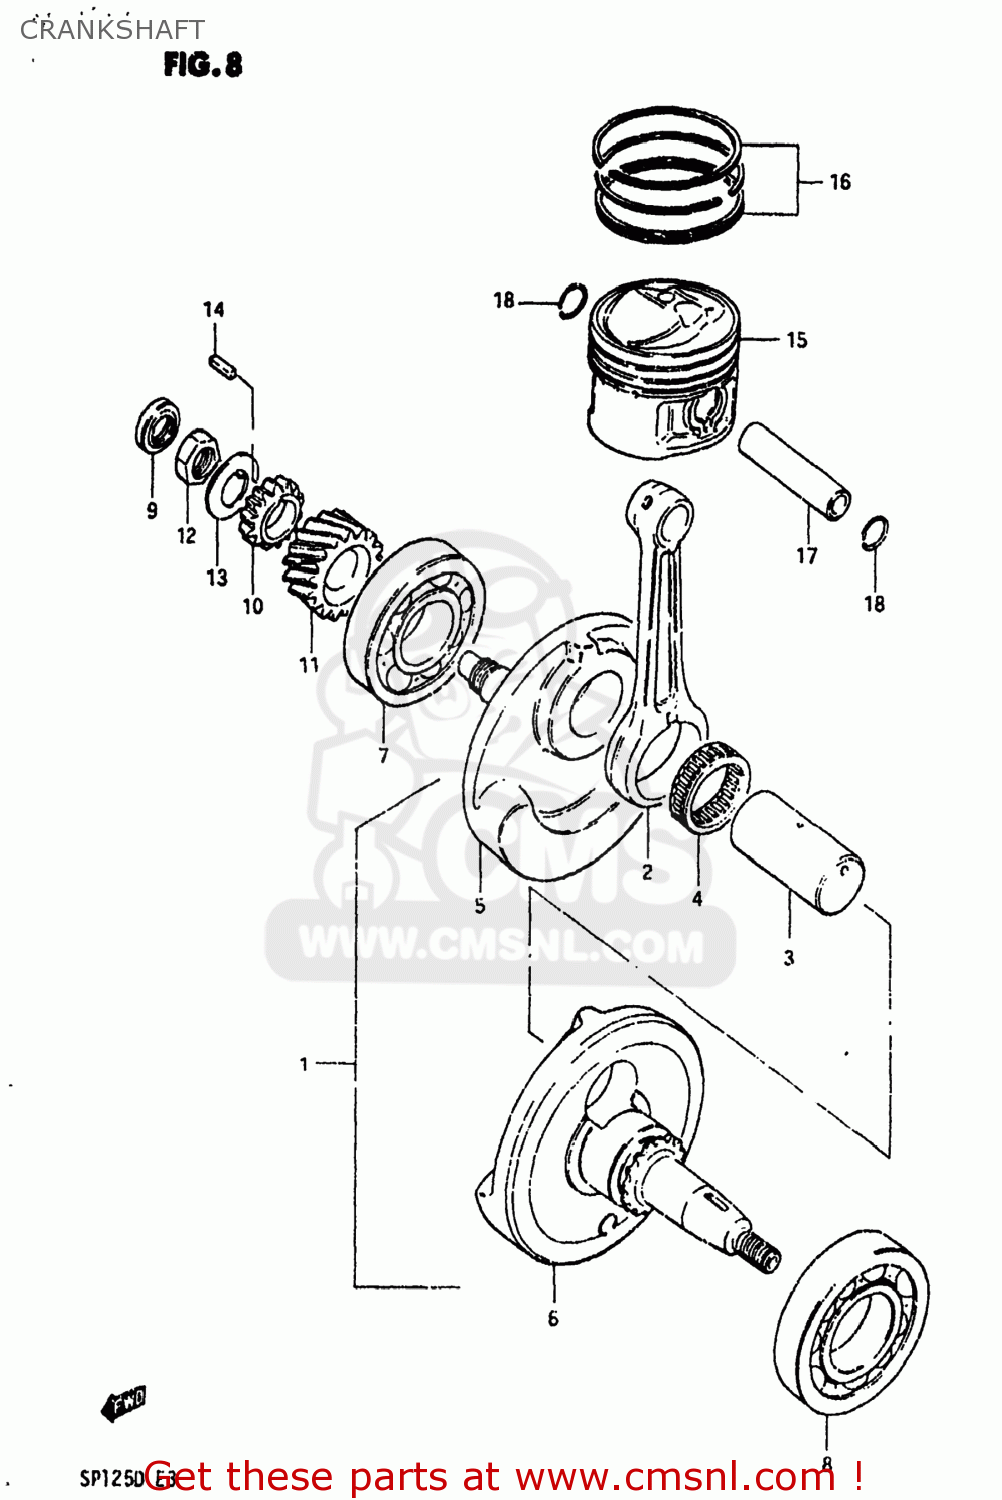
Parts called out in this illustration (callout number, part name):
1	CRANKSHAFT ASSEMBLY
2	CONNECTING ROD
3	PIN,CRANK
4	BEARING
5	CRANKSHAFT
6	CRANKSHAFT,LEFT
7	BEARING,MIDDLE
8	BEARING,LEFT
9	OIL SEAL
10	GEAR,OIL PUMP DRIVE
11	GEAR,PRIMARY DRIVE
12	NUT
13	WASHER
14	KEY
15	PISTON (STD)
16	RING SET,PISTON
17	PIN,PISTON
18	RING,SNAP 14MM
